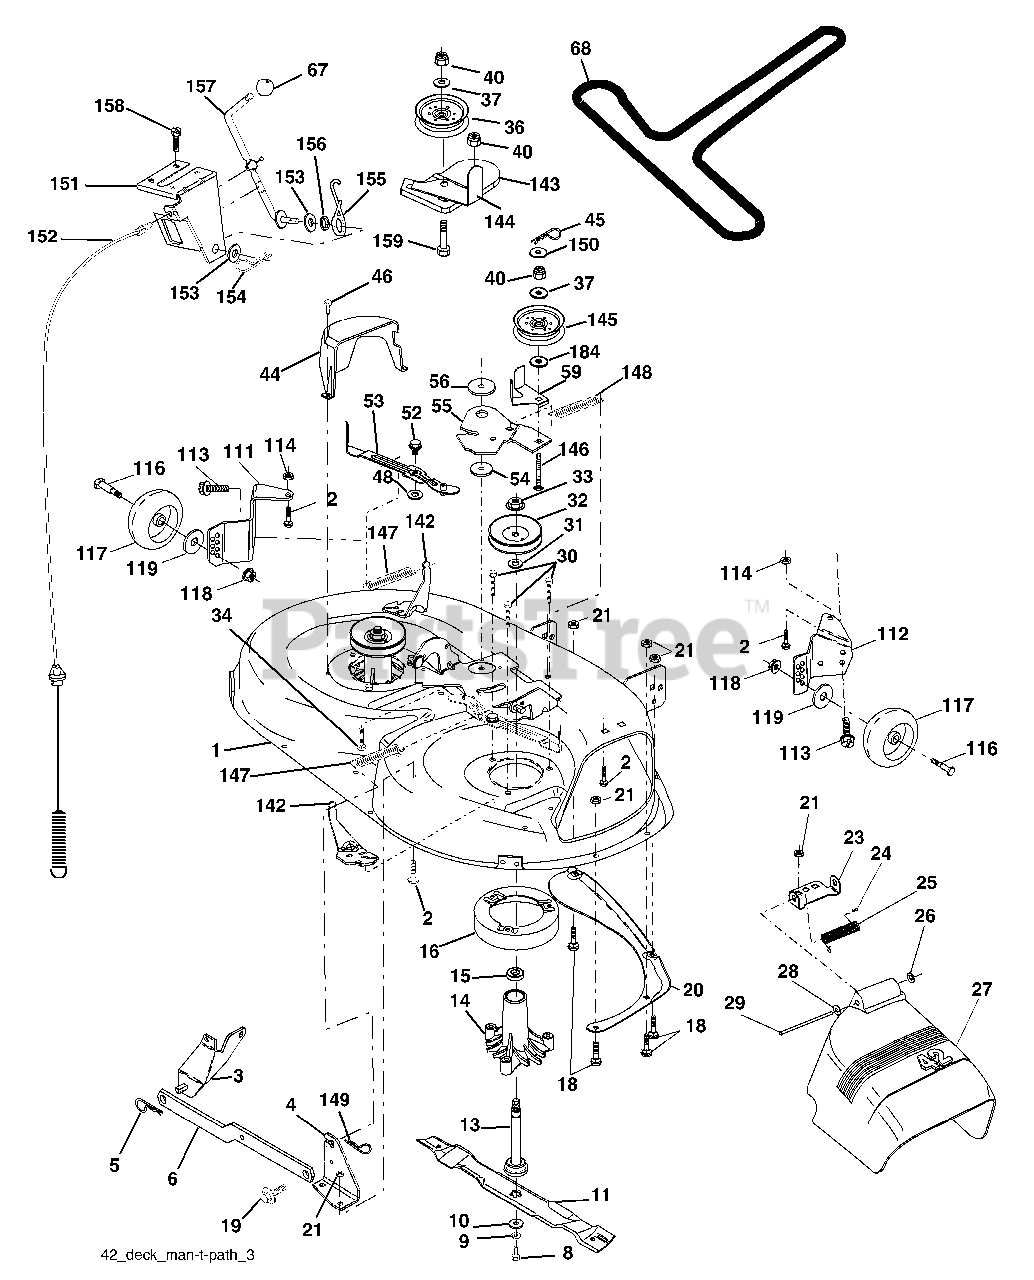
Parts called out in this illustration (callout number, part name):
1	Mower Deck Assembly, 42"
2	Bolt
3	Bracket Asm Fr. Sway Bar 3/42
4	Bracket Asm Deck 42" Sway Bar
5	Retainer Spring
6	Bar Sway Deck
8	Bolt 3/8-24 x 25 Grade 8 patched
9	Washer, Lock
10	Washer, Hardened
11	Blade, 42" Mulching Std
11	Blade, 42" Mulching Premium
11	Blade, 42" Hi-Lift
13	Shaft Assembly, Mandrel, Vented
14	Housing, Mandrel, Vented
15	Bearing, Ball, Mandrel
16	Stripper, Mandrel Deck
18	Bolt, Carriage 5/16-18 x 5/8
19	Bolt, Shoulder
20	Baffle, Vortex
21	Nut
23	Bracket, Deflector Mower 42"
24	Cap, Sleeve 80 x 112 Blk Mower
25	Spring, Torsion, Deflector 2 52
26	Nut, Push Phos & Oil
27	Shield, Deflector 42" Blk
28	Washer 11/32 x 5/8 x 16 Gauge
29	Rod, Hinge 42" 6 75 W/G
30	Screw Thdrol Washer Head
31	Washer, Spacer Mower Vented
32	Pulley, Mandrel
33	Nut, Toplock 9/16 Flange
34	Bolt
36	Pulley, Idler, Flat
37	Washer 13/32 x 13/16 x 16 Ga.
40	Nut
44	Guard, Mandrel, LH
45	Retainer
46	Screw, Thdrol 1/4-20 x 5/8 T
48	Washer, Hardened
52	Bolt, Shoulder 5/16-18 Unc
53	Arm Assembly, Brake
54	Washer, Hardened
55	Arm, Idler
56	Spacer, Retainer
59	Guard TUV Idler
67	Knob
68	V-Belt, 42" Mower
111	Bracket Wheel Gauge LH
112	Bracket Wheel Gauge RH
113	Screw 3/8-16 x .625
114	Nut keps 5/16-18 Unc
116	Bolt Shld "A" 2.41 "B" 1.66
117	Wheel Gauge Std
118	Nut Centerlock 3/8-16 Unc
119	Washer 3/8 x 7/8 x 14
142	Arm Spring Brake Mower
143	Bracket Arm Idler 42"
144	Keeper Belt 42" Clutch Cable
145	Pulley Idler Flat
146	Bolt Carriage Idler
147	Spring Extension
148	Spring Return Idler
149	Retainer Spring Yellow
150	Washer 9/32 x 3/4 x 16 Ga.
151	Bracket Clutch Cable
152	Clutch Cable 42"
153	Washer Flat 3/8" Type B
154	Spring Retainer
155	Spring Retention LVR CLTCH CAB
156	Spacer Clutch Cable
157	Rod Clutch Cable 3/8"
158	Screw Hex Thd Cut 1/4-20 x 1/2
159	Bolt Rdhd Sqn 3/8-16 Unc x 1-3/4
184	Washer 13/32 x 7/8 x 10 Ga.
